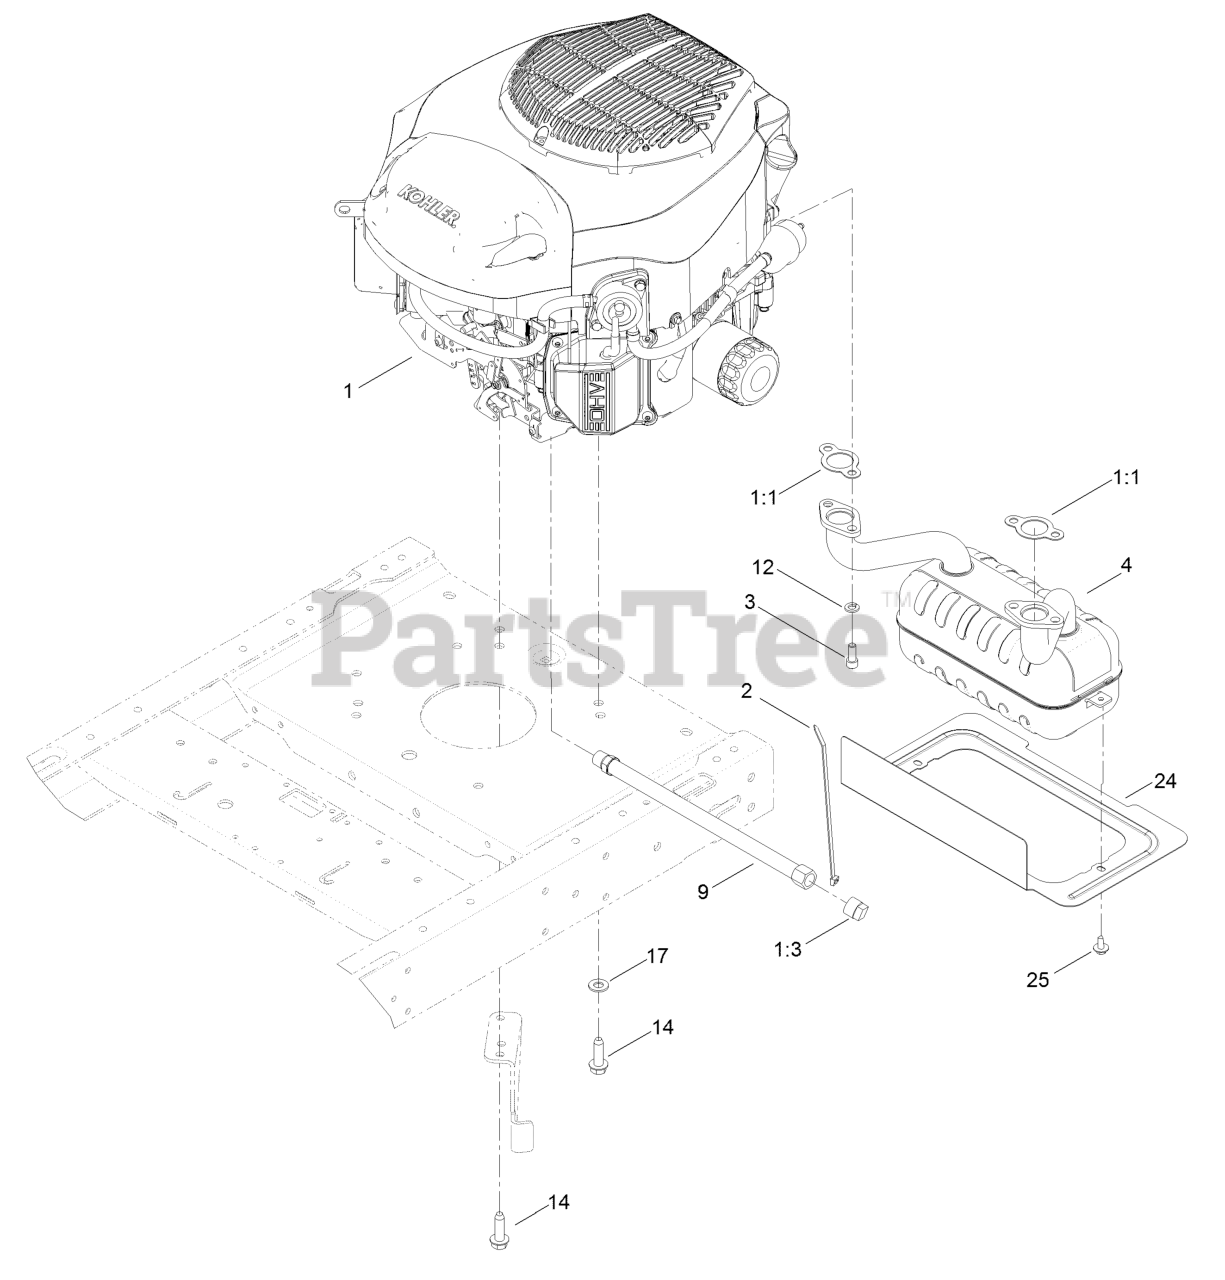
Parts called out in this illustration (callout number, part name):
1:1	GASKET-EXHAUST
1:3	PLUG-PIPE, SQH
2	TIE-CABLE
3	SCREW-HSH
4	MUFFLER-KOHLER
9	HOSE-DRAIN, OIL
12	WASHER-LOCK
14	SCREW-THD
17	WASHER-FLAT
24	SHIELD-HEAT
25	SCREW-HHFTF
